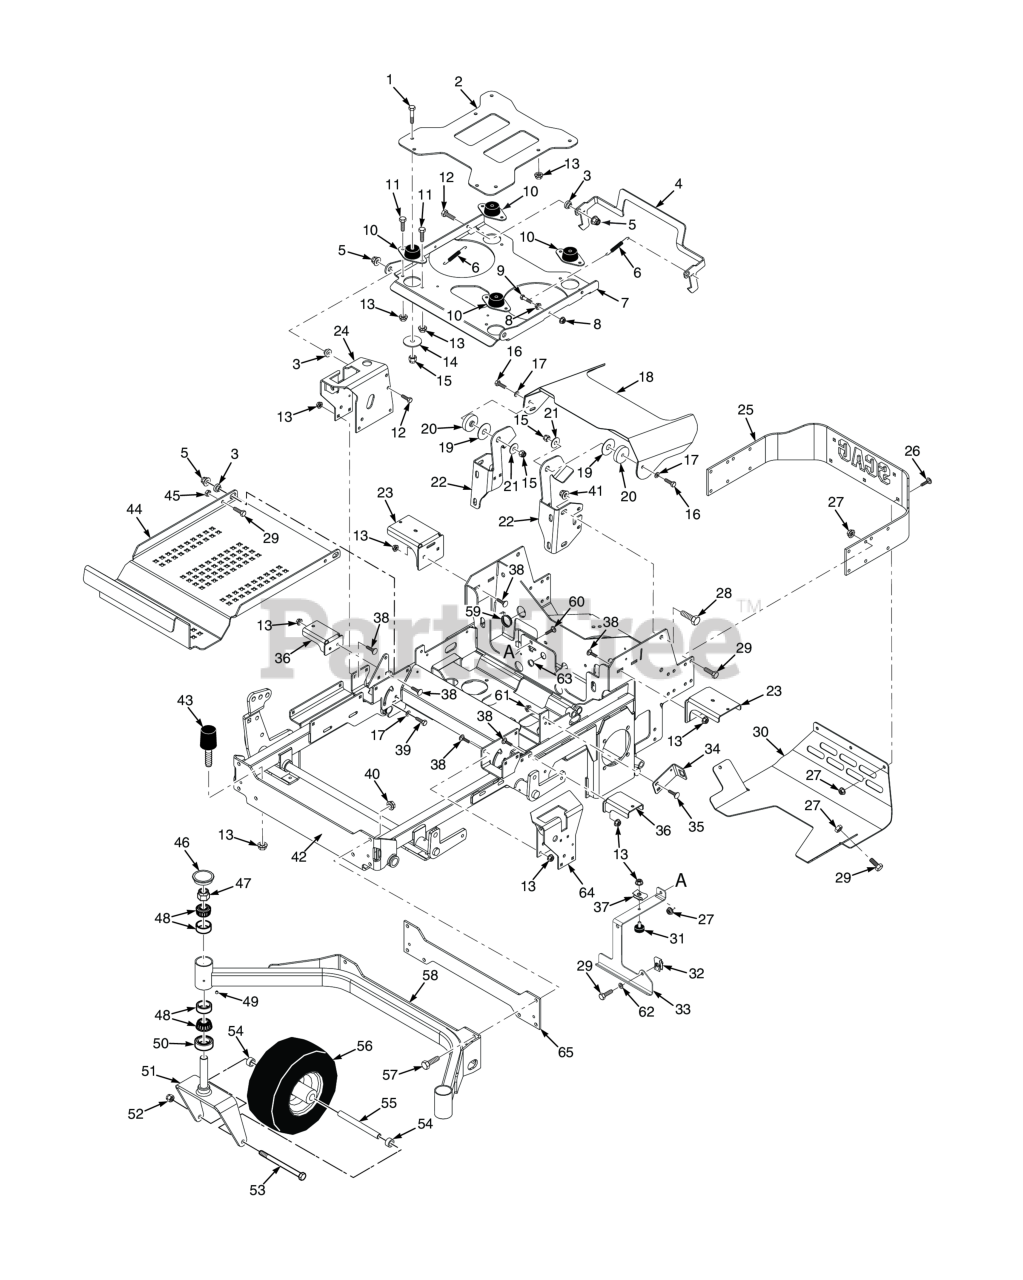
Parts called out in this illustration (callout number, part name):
1	Bolt, Hex Head 3/8-16 x 2-1/4" - 61"
2	Seat Plate w/decal
3	BUSHING, SPEED ADJUSTMENT LEVER
4	Seat Latch
5	Nut, Flange Elastic Stop Nut, 3/8-16
6	Spring, Seat Latch
7	Plate, Seat Mounting w/decals
8	NUT, 1/4-20 SERRATED FLANGE HEX HEAD
9	SERR. FLG. HEX HEAD CAPSCREW, 5/16-18 X 3/4
10	Isolator, Seat
11	BOLT, SERRATED FLANGE HEX HEAD 5/16-18 X 3/4"
12	Bolt, Hex Head 3/8-16 x 1-1/4", Kawasaki FX / FT & FT-EFI
13	Nut, Serrated Flange 5/16-18 (Right Front Engine Mounting, Briggs and Kohler Only)
14	Flatwasher, 3/8-.406 x 2.25" x .1875
15	HEX NUT, ELASTIC STOP LOCK, 3/8-16
16	Bolt, Hex Head 3/8-16 x 1-3/4" (Kohler EFI)
17	Flatwasher, 3/8" Special (.391 x .938 x .105)
18	Hood Assembly
19	Disc, Anti-Friction
20	Spacer, Hood
21	Flatwasher, 3/8-.406 x 1-1-1/2 x 7 Gauge
22	ROPS Mount, RH, 22 & 23FX/ 23CV / 24FT / 26FT-EFI / 25CV-EFI
23	Mounting Bracket, Fuel Tank Rear
24	Control Plate w/decal, RH
25	Bumper, Rear
26	Carriage Bolt, 3/8-16 x 1.0"
27	NUT, 3/8-16 SERRATED FLANGE HEX HEAD
28	Bolt, Hex Head 1/2-13 x 1-1/4"
29	Bolt, Hex Head, 3/8-16 x 1 Gr. 5
30	Plate, Skid
31	Bumper, Rubber 5/16-18 x 5/8"
32	U-Nut, 3/8-16 (short)
33	BATTERY HOLD DOWN
34	Bracket, Operator Presence Switch
35	Serr. Fl. Hex Head CPSCR, 1/4-20 x 3/4"
36	Mounting Bracket, Fuel Tank Front
37	Cable Clamp, Double
38	Bolt, 5/16-18 x .75 RHSN Carriage
39	Bolt, Hex Head 3/8-16 x 1-1/2" B&S 32BV
40	Nut, 7/16-14 Flange Elastic Stop
41	Nut, Elastic Stop 1/2-13, (STT-52 & STTII-52)
42	Main Frame Assembly w/decals (61")
43	Rubber Isolator
44	Footplate
45	Nut, Jam 3/8-16
46	Cap, Grease
47	Nut, Elastic Stop 1.0"-14
48	Bearing Set
49	Plug, 1/4-28 THD Form
50	Seal, 2.00" O.D. x 1.625" Bore
51	Yoke Weldment, (Black))
52	HEX LOCKNUT, ELASTIC STOP, 1/2-13
53	Bolt, Hex Head 1/2-13 x 9-1/2" (61V & 72A/VS)
54	Spacer, Caster Wheel
55	Sleeve, Caster Wheel (61V, 72A/VS)
56	Wheel Assy, 61V, 72V (Incl. 20, 54, 55)
57	BOLT, HEX HEAD, 7/16-14 X 1-1/4
58	Caster Support Weldment (48"/52")
59	Bushing, Thick Panel Snap
60	Bolt, Carriage 3/8-16 x 3/4"
61	HEX, NUT, ELASTIC STOP LOCK, 1/4-20
62	Lockwasher, 3/8" Spring, Kawasaki FX / FT & FT-EFI / B&S 32BV
63	Bushing, Thick Panel Snap - 1"
64	Control Plate w/decal, LH
65	Weight, Caster - Yamaha Models Only
